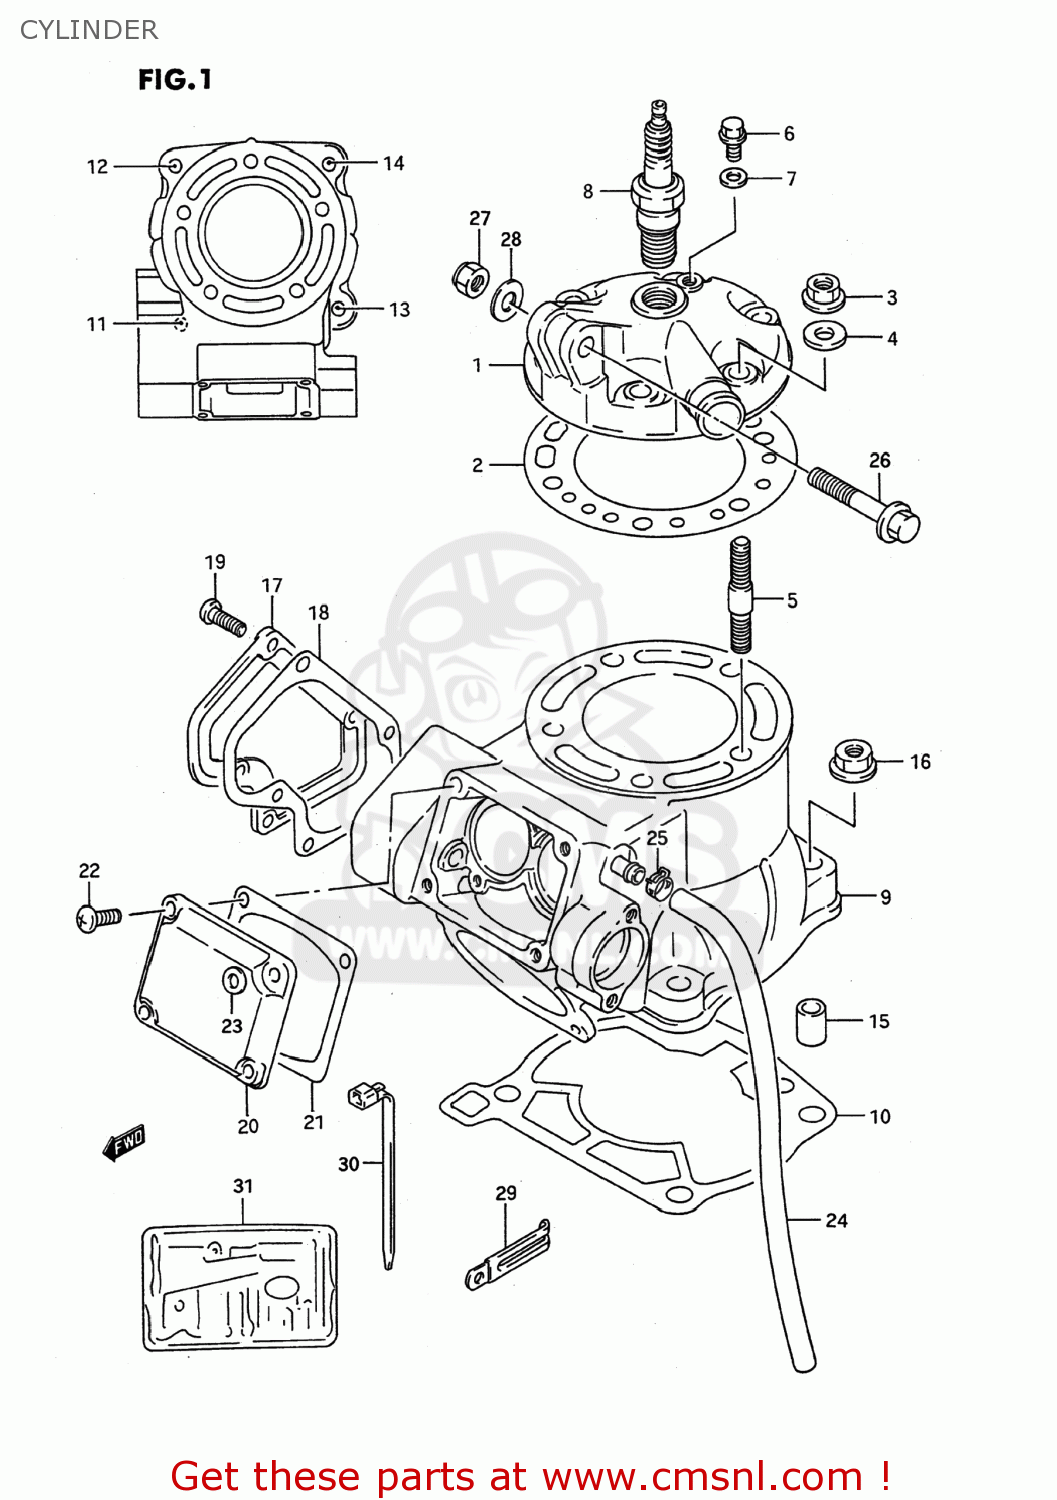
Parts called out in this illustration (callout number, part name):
1	HEAD,CYLINDER
2	GASKET,CYLINDER HEAD
3	NUT
4	WASHER
5	BOLT,STUD
6	UNION
7	GASKET(6.2X11X1).2 (NAS)
8	SPARK PLUG BR9EV
9	CYLINDER
10	GASKET,CYLINDER (NAS)
11	STUD 10X30
12	STUD BOLT
13	STUD BOLT (L:40)
14	BOLT,STUD
15	PIN
16	NUT
17	COVER,CYLINDER NO.1
18	GASKET,CYLINDER COVER (NAS)
19	BOLT
20	COVER,CYLINDER
21	GASKET,CYLINDER COVER (NAS)
22	SCREW
23	GASKET(5.3X9.3X1.2) (NAS)
24	HOSE
25	CLIP
26	BOLT 8X45
27	NUT
28	WASHER
29	CLAMP
30	CLAMP(L:125)
31	GASKET SET (NAS)
